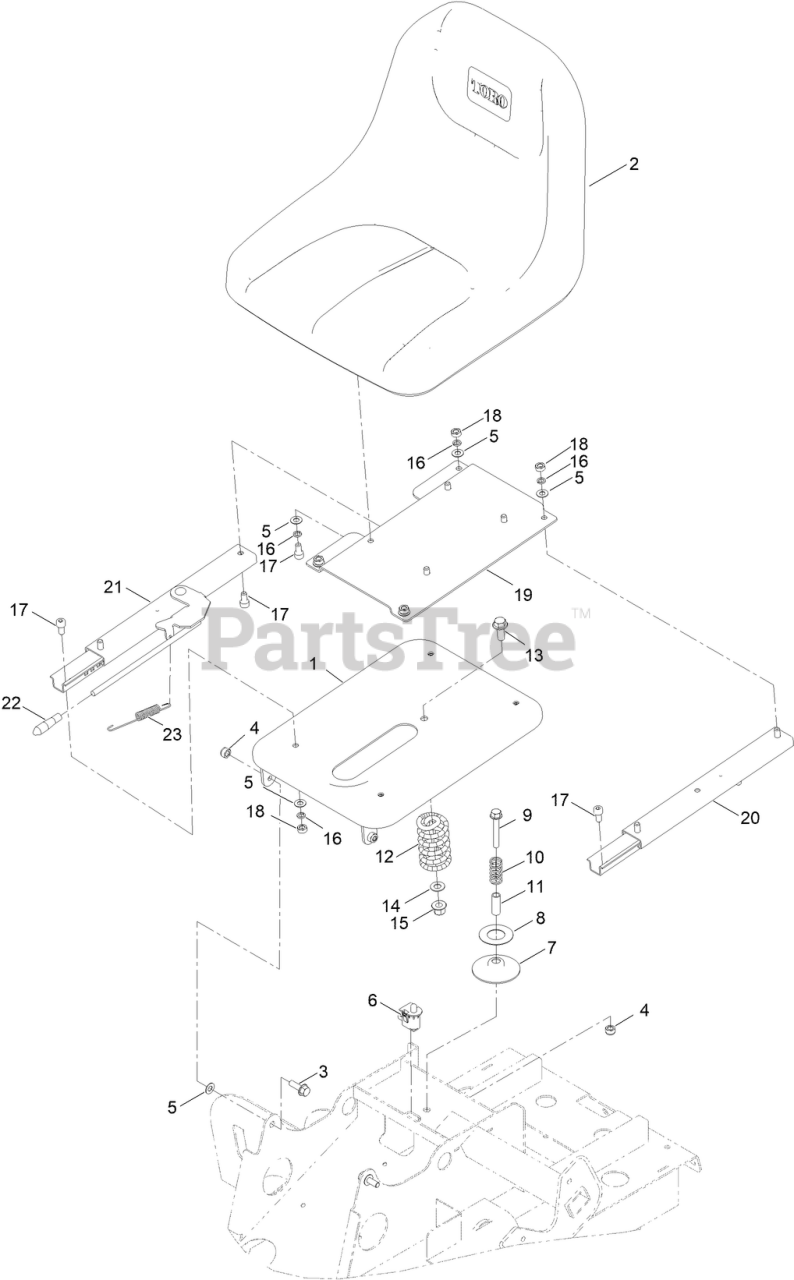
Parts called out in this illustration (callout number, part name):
1	SUPPORTING PLATE, SEAT
3	SCREW-HHF
4	NUT-HEX, NI
5	WASHER-PLAIN
6	SEAT SENSOR
7	PLATE, SPRING SEAT
8	WASHER
9	SCREW-HHF
10	SMALL SPRING, SEAT
11	SHAFT, SPRING
12	SPRING, SEAT
13	SCREW-HHF
14	WASHER-PLAIN
15	NUT-FLANGE, NI
16	WASHER-SPRING
17	BOLT SEAT, SLIDE MOUNT
18	NUT-HEX
19	MOUNTING PLATE, SEAT
20	SEAT SLIDE ASM, LH
21	SEAT SLIDE ASM, RH
22	ADJUSTMENT LEVER CAP, SEAT
23	ADJUSTMENT SPRING, SEAT
